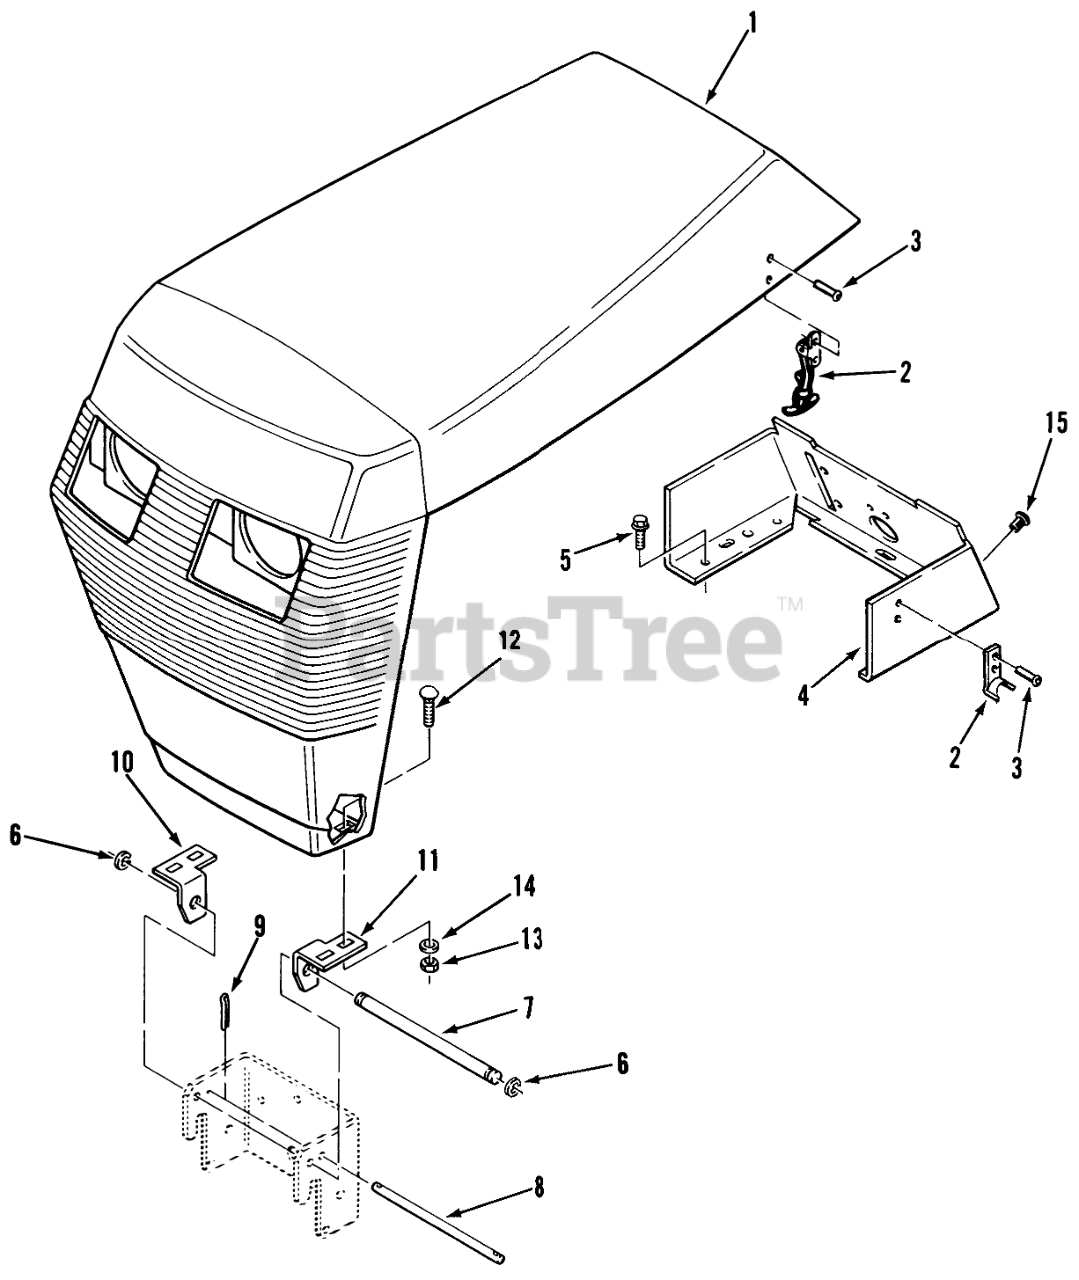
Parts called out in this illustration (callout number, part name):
2	ASSY-FLEX DRAW LATCH
2	ANGL-BLT GURDB
3	RIVET -4
4	Console
5	SCREW
6	RING-RETAINING
7	GRILL PIVOT ROD
8	ROD-HOOD STOP
9	Cotter Pin
10	BRKT-GRILL PIVOT R
11	BRKT-GRILL PIVOT R (NS)
12	Bolt 1/4-20 X 5/8
12	Bolt
14	Nut
15	NYLON PLUG
